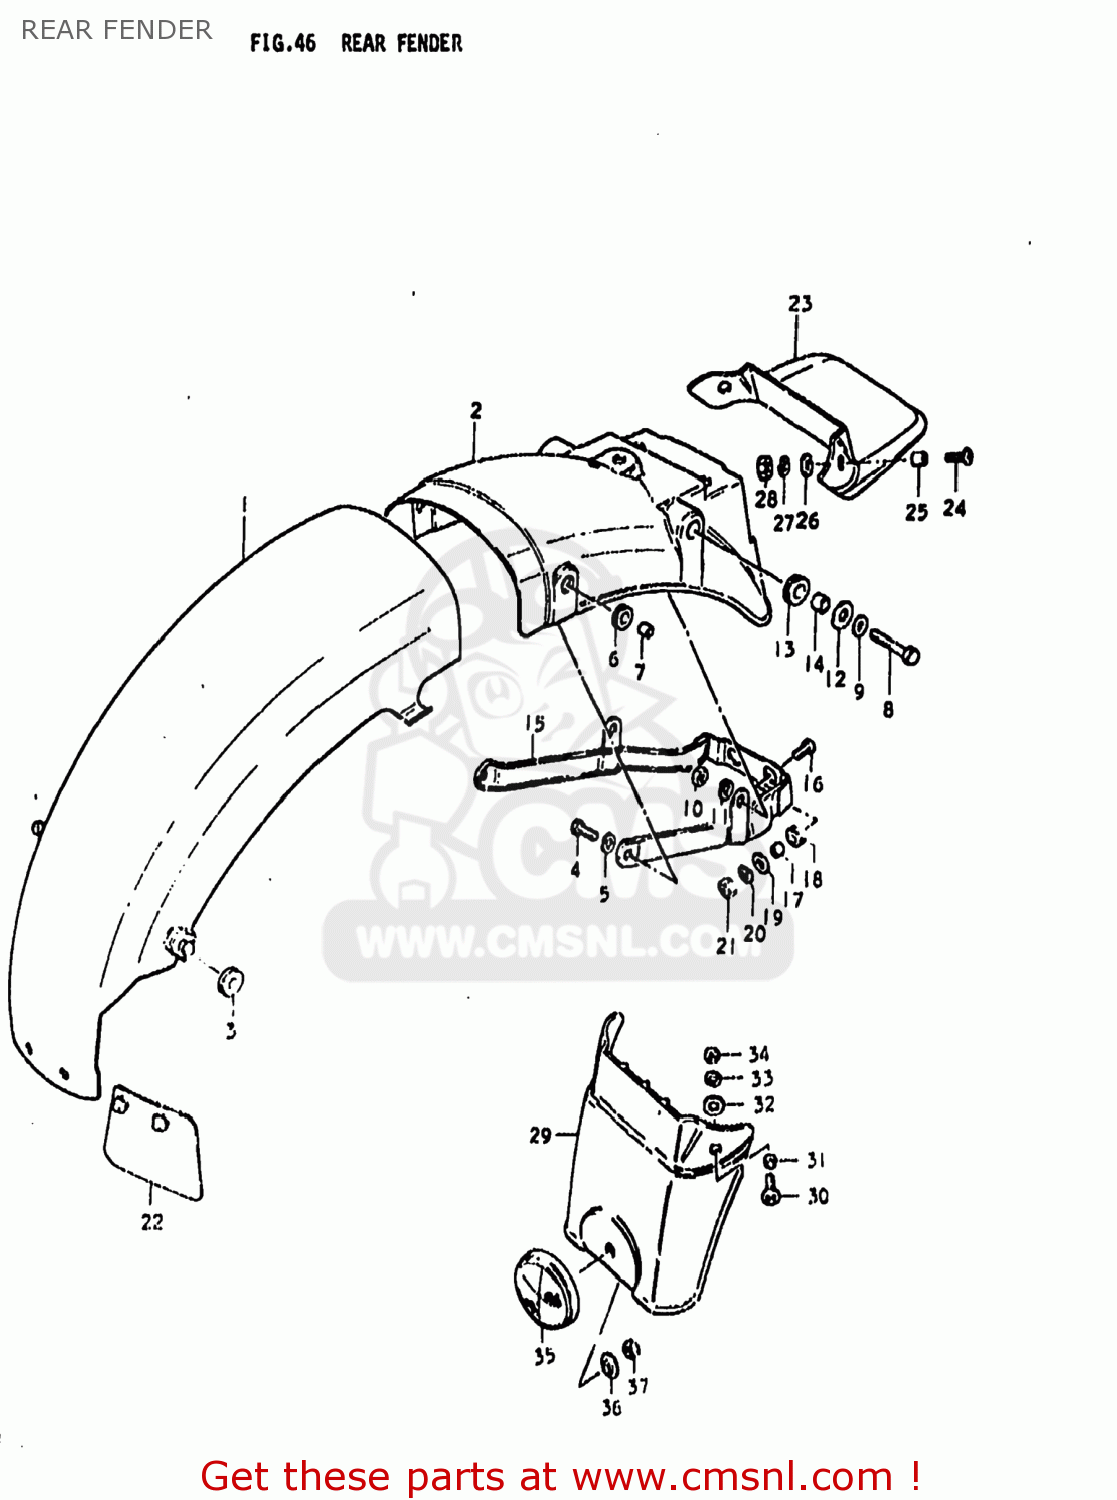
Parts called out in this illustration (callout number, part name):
1	FENDER,REAR
2	BODY,RR FENDER RR
3	CUSHION
4	BOLT
5	LOCK WASHER
6	CUSHION
7	SPACER(6.1X9X7.5)
8	BOLT
9	WASHER
10	NUT
11	LOCK WASHER
12	WASHER(8.5X26X1.2)
13	CUSHION
14	SPACER (8.2X12X7.5)
15	REINFORCEMENT,REAR FENDER
16	SCREW
17	SPACER (6.1X9X9)
18	CUSHION
19	WASHER(6,5X22X1.6)
20	LOCK WASHER
21	NUT
22	GUIDE,RR FENDER MUD
23	EXTENSION,REAR FENDER
24	SCREW (6X15)
25	SPACER(6.2X8.3X5.7)
26	WASHER(6.5X18X1)
27	LOCK WASHER
28	NUT
29	EXTENSION,REAR FENDER
30	SCREW (6X15)
31	SPACER(6.2X8.3X5.7)
32	WASHER(6.5X18X1)
33	LOCK WASHER
34	NUT
35	REFLEX REFLECTOR,RR
36	SPACER
37	NUT
